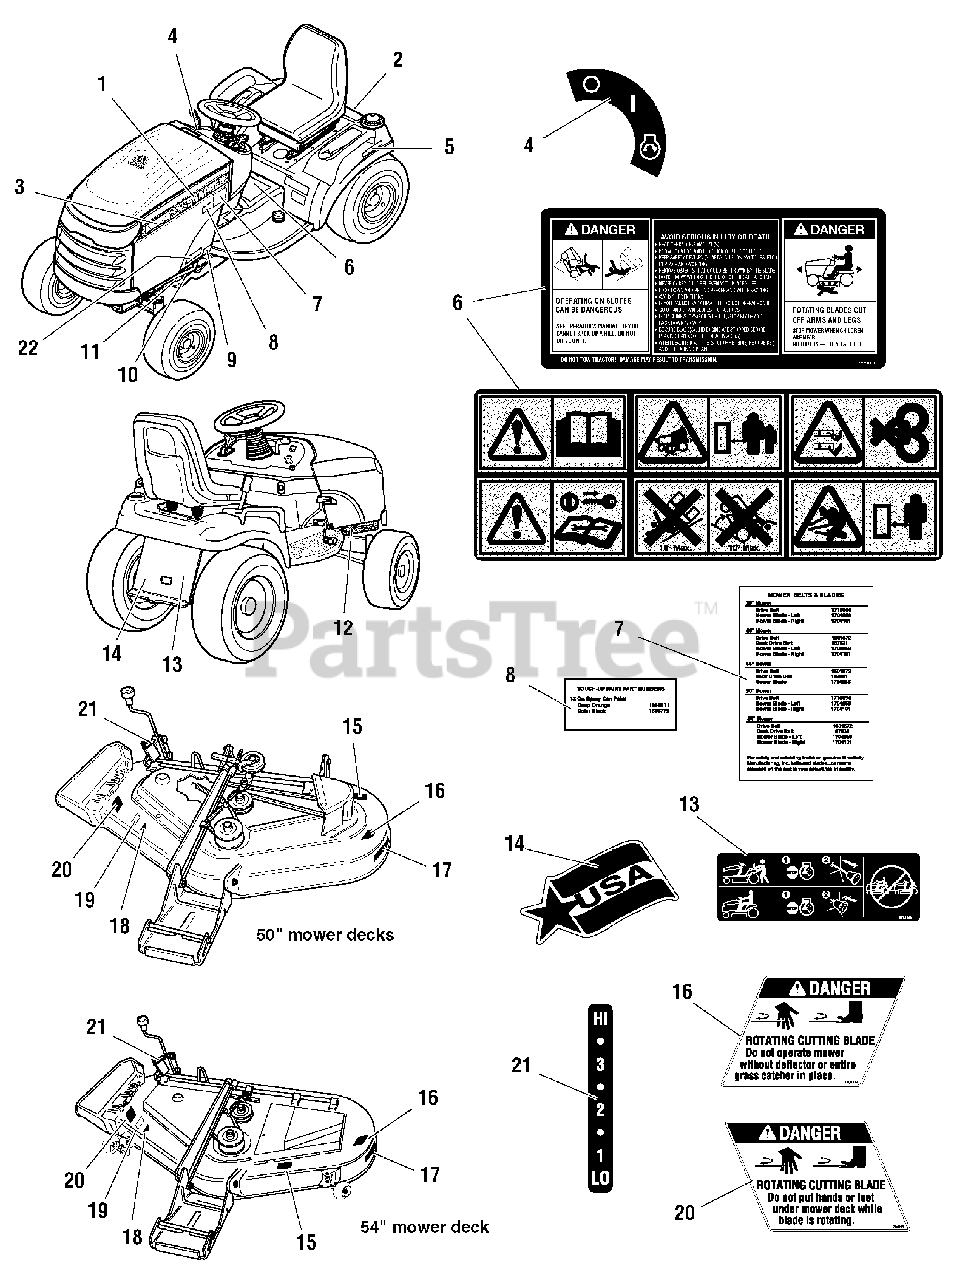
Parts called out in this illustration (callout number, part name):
1	DECAL, Snapper
2	DECAL, Hood Stripe, Snapper, LH
2	DECAL, Hood Stripe, Snapper, RH
3	DECAL, GT2354
4	DECAL, Ignition Switch Symbols, White/Black
5	DECAL, Automatic Control Traction
6	DECAL, Tunnel Cover, Danger Slopes/Blades
6	DECAL, Tunnel Cover, Danger Slopes/Blades, (Export)
7	DECAL, Drive Belts, Mower Blades
8	DECAL, Touch Up Paint, Red
9	DECAL, Protective Sticker
10	* DECAL, I.D. Plate
11	* LABEL, Decibel, Power Mass (Export Only)
12	* DECAL, Patent
13	DECAL, Transmission Release Valve
14	DECAL, USA Logo Stars & Stripe
15	* DECAL, I.D. Plate
16	DECAL, Danger Do Not Operate Without Deflector
17	DECAL, Free Floating Mower, Silver
18	* DECAL, OPEI Certified
19	DECAL, 54", Silver on Black with Stripe
20	DECAL, Danger Do Not Put Hands/Feet in Mower
21	DECAL, 1 2 3 4 5 6, Height of Cut
22	DECAL, Power Steering
